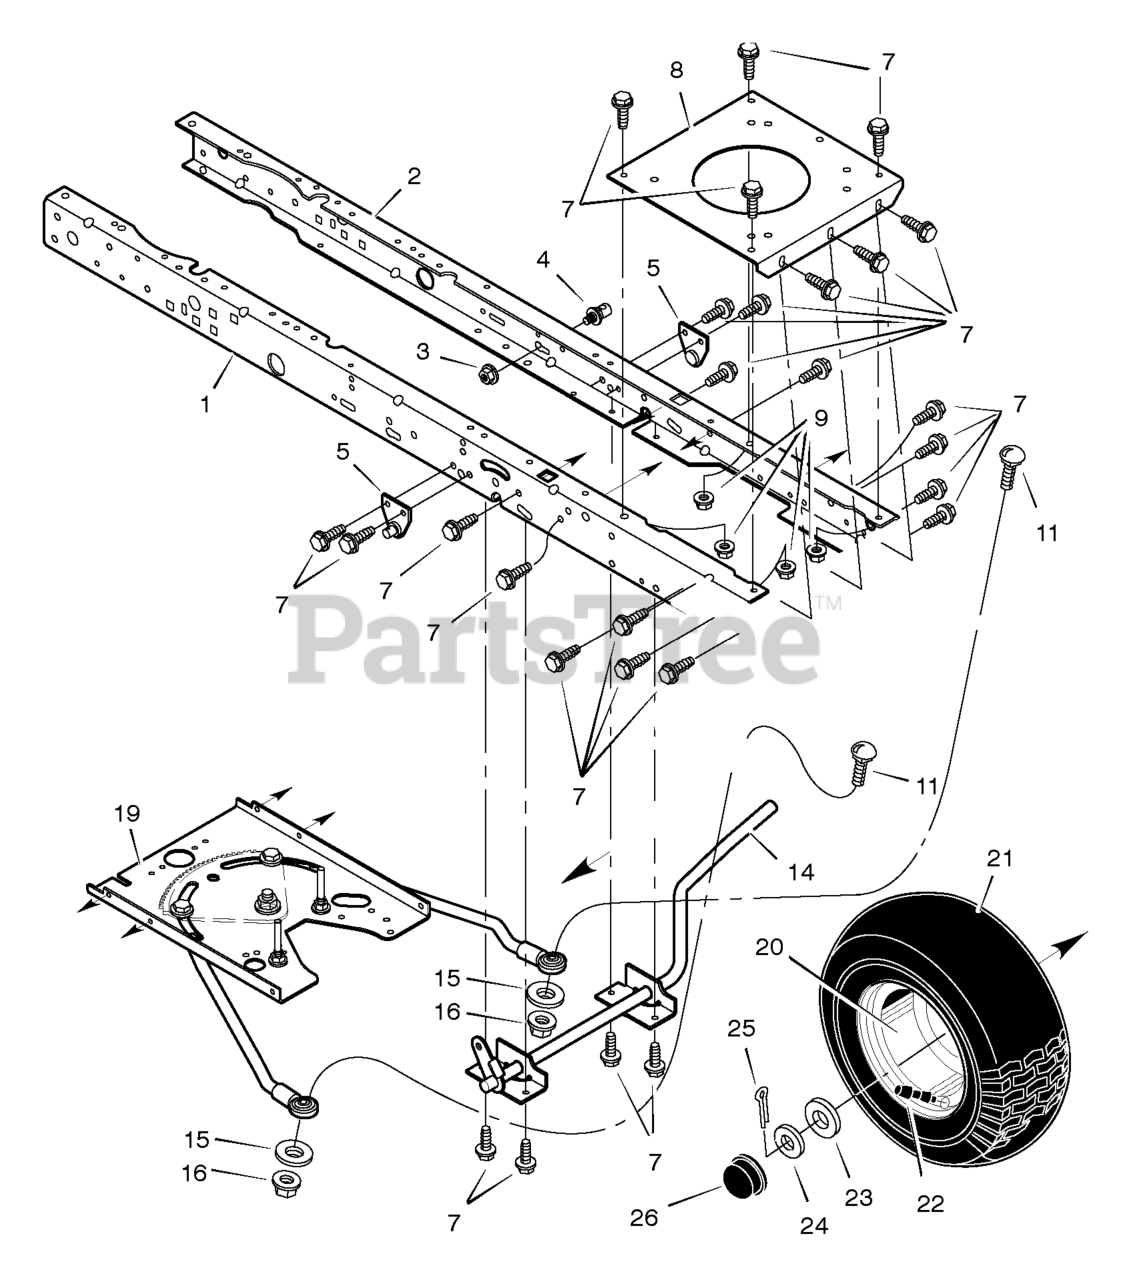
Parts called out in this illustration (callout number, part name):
1	Frame, Right
2	Frame, Left
3	Nut, Flange
4	Stud, Swivel
5	Bracket Ass'y, Suspension
8	Plate, Engine
9	Nut
11	Bolt, Carriage
14	Lever, Brake/Clutch
15	Washer
19	Assembly, Steering *
20	Wheel & Tire Assembly
22	Stem, Valve
25	Pin, Cotter
26	Cap, Hub
